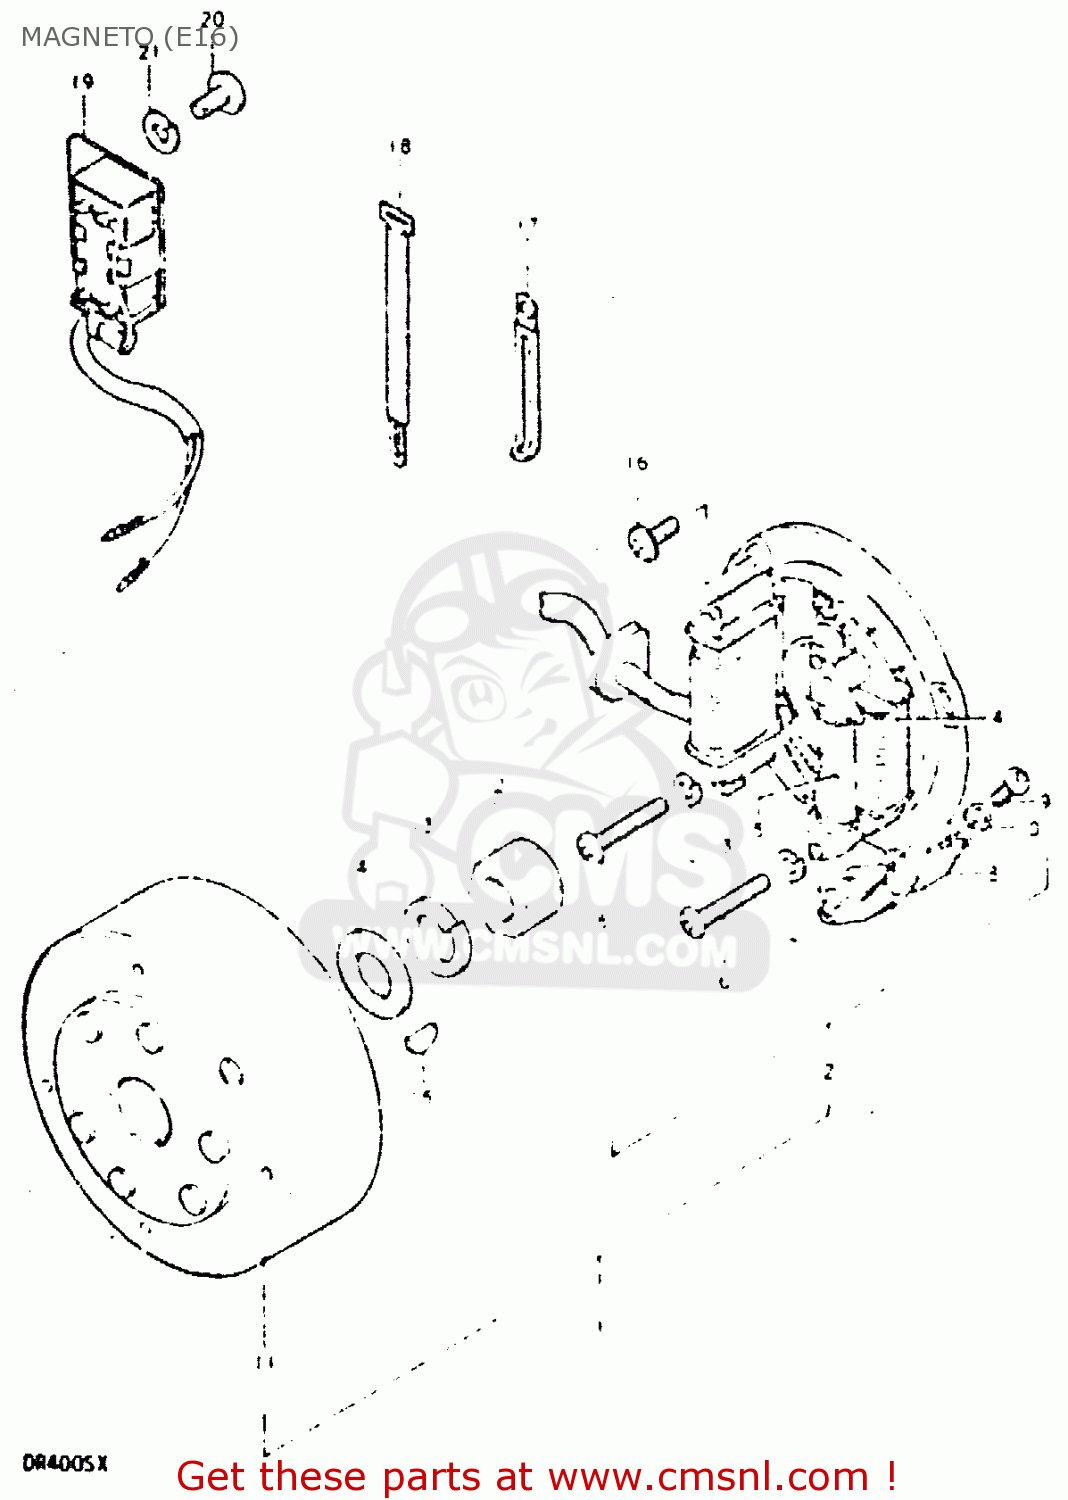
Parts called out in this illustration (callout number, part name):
1	MAGNETO ASSY
2	STATOR ASSY
3	COIL, LIGHTING
4	COIL,PRIMARY
5	COIL,PULSER
6	SCREW
7	LOCK WASHER
8	COIL,PULSER
9	SCREW
10	LOCK WASHER
11	FLYWHEEL, MAGNETO
12	NUT
13	LOCK WASHER
14	WASHER(14X27X3)
15	KEY 4MM
16	SCREW(5X14)
17	CLAMP
18	CLAMP L:110
19	REGISTER ASSEMBLY
20	SCREW 6X12
21	LOCK WASHER
